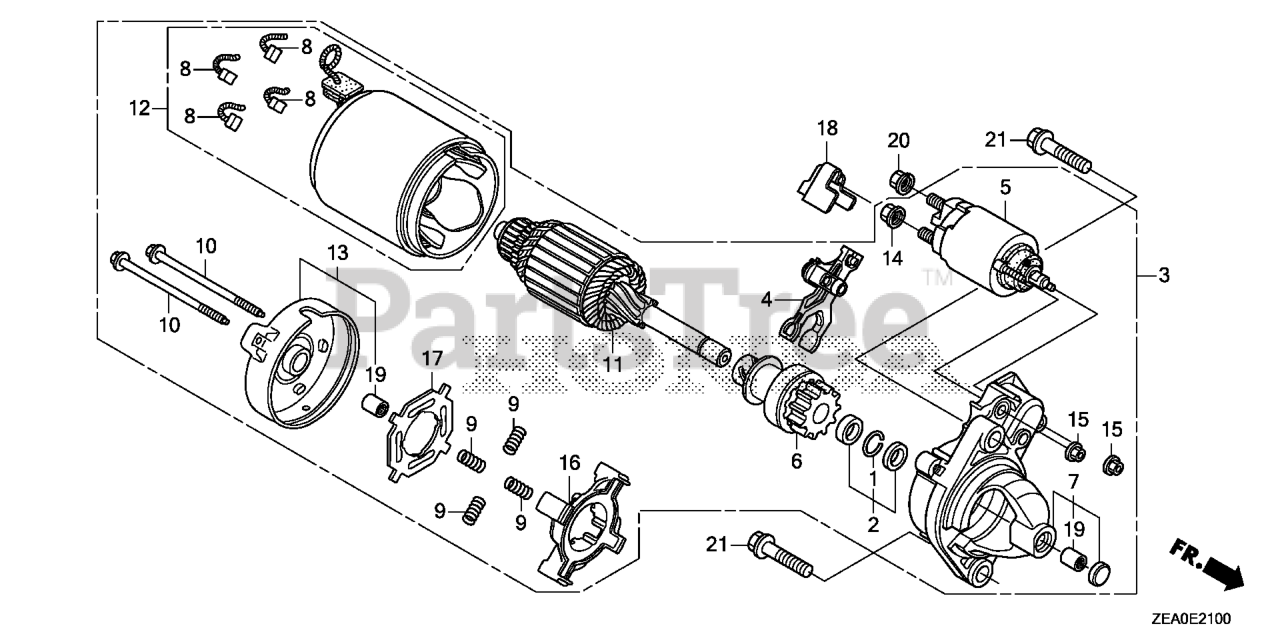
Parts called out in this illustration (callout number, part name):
1	RING, SNAP (DENSO)
2	COLLAR SET, CLUTCH STOP
3	STARTER MOTOR ASSY.
4	LEVER, PINION DRIVE
5	SWITCH ASSY., MAGNET
6	CLUTCH, OVERRUNNING
7	HOUSING, DRIVE SIDE
8	BRUSH
9	SPRING, BRUSH
10	BOLT, THROUGH
12	YOKE
13	FRAME, COMMUTATOR END
14	NUT, HEX. (8MM)
15	NUT, FLANGE (5MM)
16	HOLDER, BRUSH
17	INSULATOR, BRUSH HOLDER
18	COVER, TERMINAL
19	BEARING A
20	NUT-WASHER (8MM)
21	BOLT, FLANGE (10X40)
